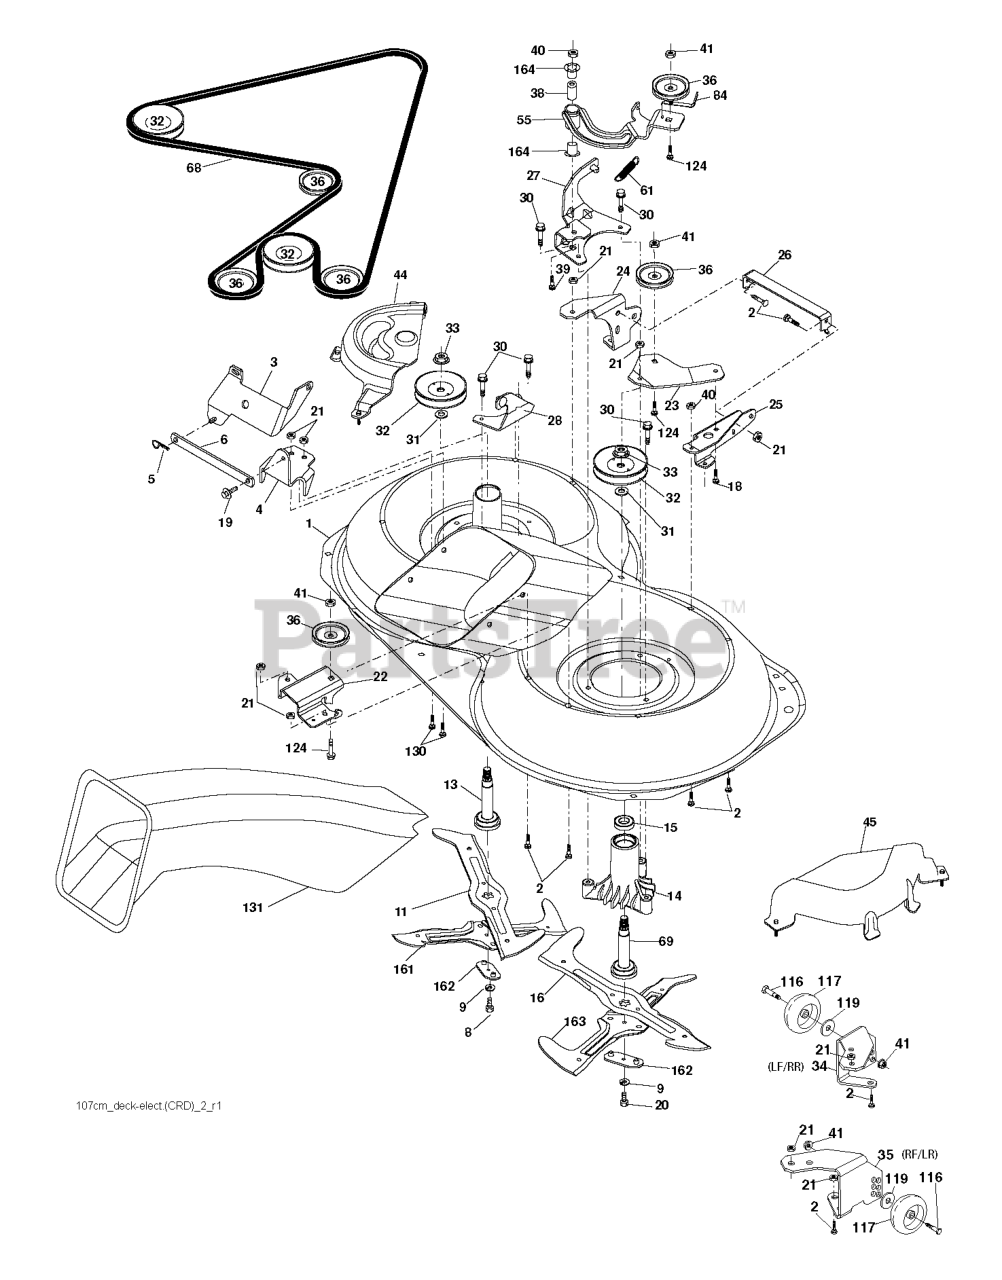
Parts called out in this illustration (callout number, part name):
1	Housing Asm. Mower 107 CRD
2	RP BOLT 5/16-18 X3/4 ZN/YEL GR
3	BRACKET.ASM.BAR.SWAY.CHASS
5	RETAINER-SPRNG RB
6	BAR.SWAY.92.CRD
8	BOLT.3/8-24X1.25 GR8
9	LOCKWASHER
11	BLADE.3N1.LH.CRD
13	SHAFT ASM VENT
14	HOUSING.MANDREL.VENTED (MACHD)
16	BLADE.3N1.RH.CRD
19	BOLT SHD 5/16-18
20	BOLT.3/8-24X1.25GR8. LHTHRD
21	LOCKNUT
22	BRACKET.IDLER.RR.107.CRD
24	BRACKET
25	BRACKET RF
26	SUPPORT
28	BRACKET
30	SCREW, WASHER HEAD
31	WASHER.SPACER.MANDREL
32	PULLEY.MANDREL.4.80 PD.2006
33	NUT.FLANGE.LOCK.TOP
34	BRACKET
35	BRACKET
36	PULLEY.IDLER.4.25
41	NUT LOCK FLG 3/8-16 UNC
45	COVER.MANDREL.RH.CRD
46	SCREW.1/4-20X5/8
55	ARM.IDLER.107.CRD
61	SPRING
68	HEX-BELT 107 MOWER
69	SHAFT.ASM.W/LWR.BRG.RH.THREAD
84	KEEPER, BELT IDLER
116	BOLT.SHOULDER.3/8-16X3-5/8.
117	RP WHEEL. GUAGE RALLY
118	NUT LOCK FLG 3/8-16 UNC
119	WASHER
124	BOLT.3/8-16X1.50
130	BOLT.CARR.SQNK.5/16-18UNC.X3/4
131	CHUTE BAGGER
163	BLADE.CROSS.RH.CRD.107
164	BRNG T
